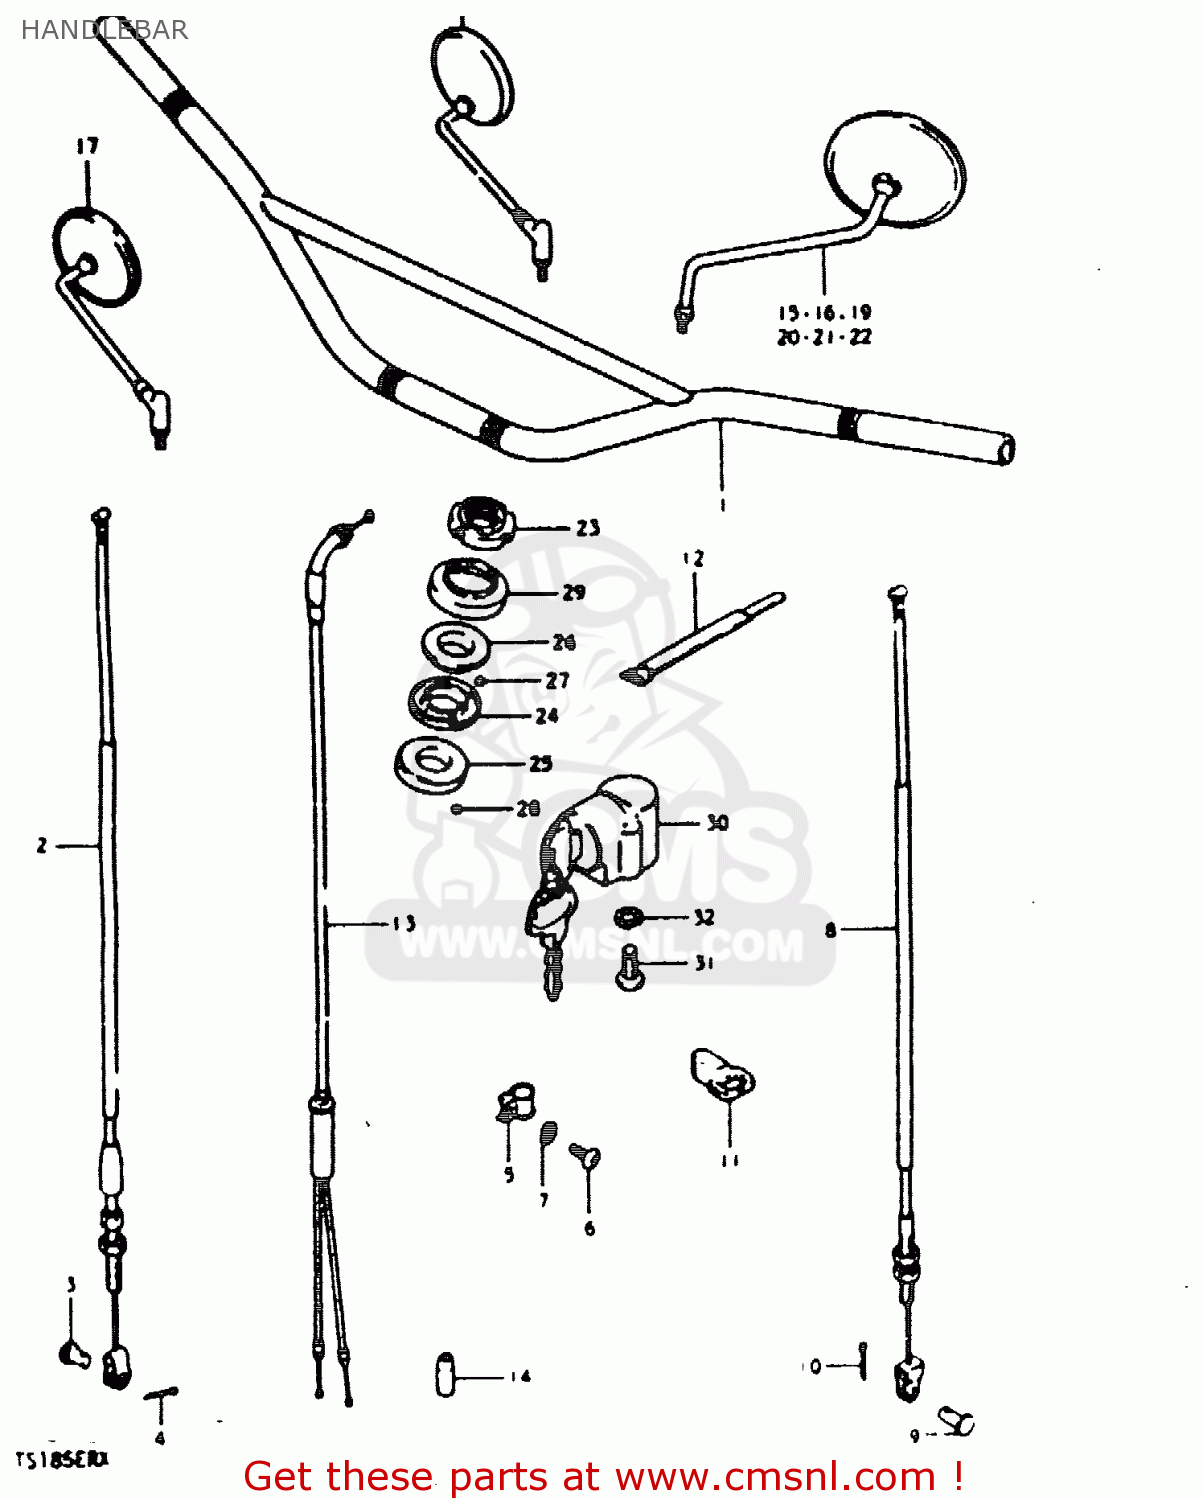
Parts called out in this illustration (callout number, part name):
1	HANDLEBAR
2	CABLE,FRONT BRAKE
3	PIN(L:13.5)
4	PIN
5	GUIDE,CABLE
6	SCREW
7	LOCK WASHER
8	CABLE ASSEMBLY,CLUTCH
9	PIN(L:15)
10	PIN
11	GUIDE,CLUTCH CABLE
12	CLAMP
13	CABLE ASSEMBLY,THROTTLE
14	SEAL,DUST(7X18X30)
17	MIRROR ASSY,RH
23	NUT,STEERING STEM(25X44X10)
24	RACE,STEERING INNER UPR
25	LACE,STEERING INNER LWR
26	RACE,STEERING OUTER UPR
27	BALL
28	BALL
29	DUST SEAL,STEERING UPR
30	LOCK ASSEMBLY,STEERING
31	SCREW
32	LOCK WASHER
